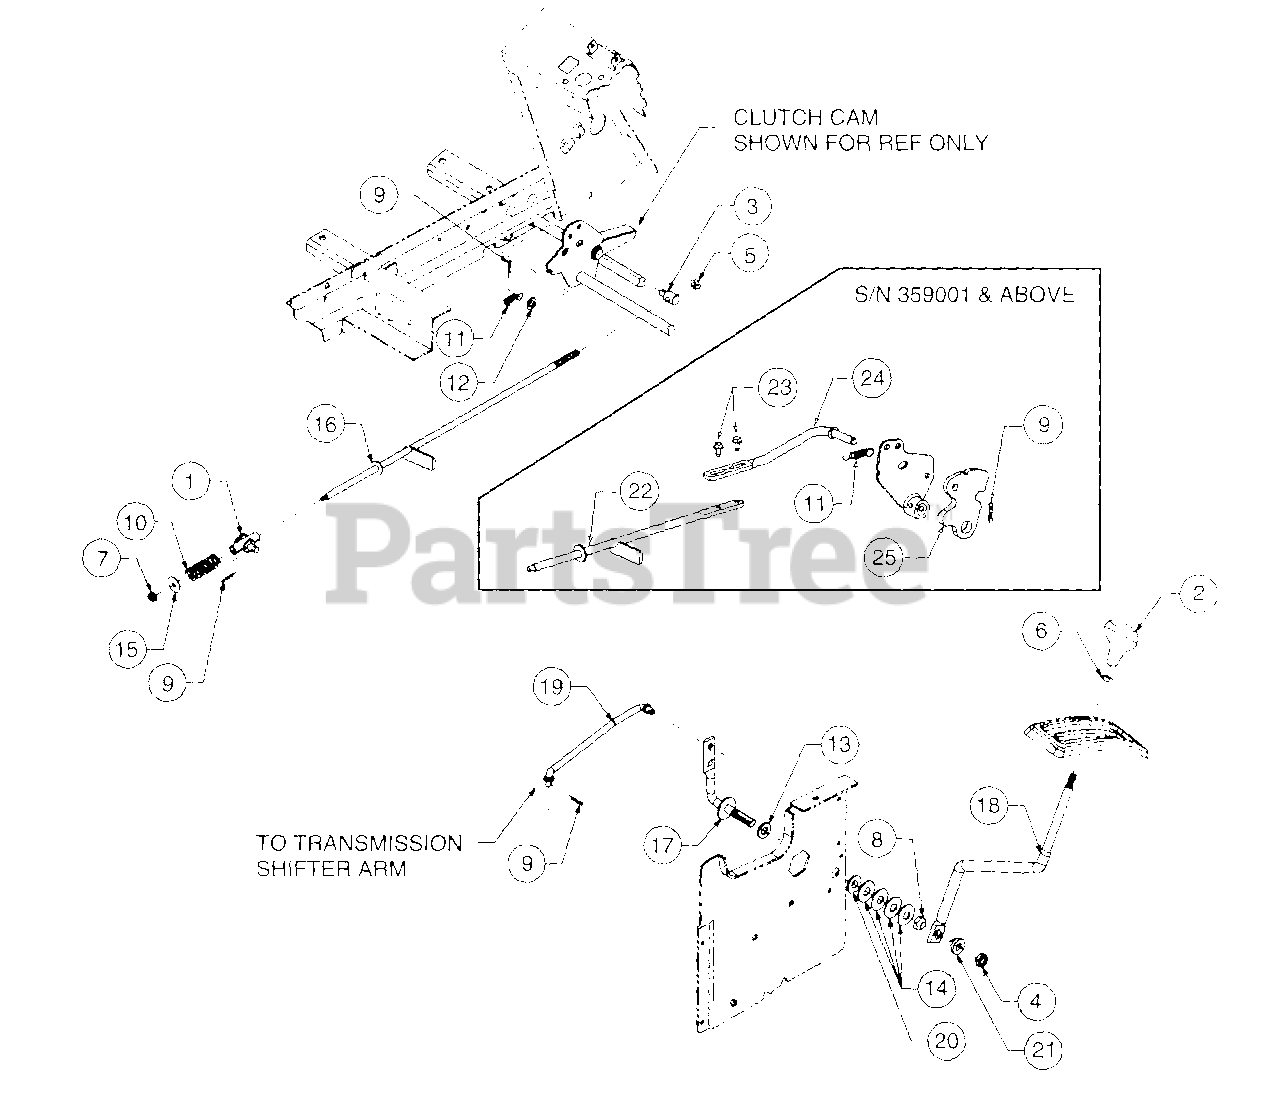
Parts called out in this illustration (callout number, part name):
1	Pivot Assy, Sleeve
2	Knob, Shifter
3	Ferrule, Adjustment
4	Nut, Hex Top Lock, 1/2-20
5	Nut, Hex Jam, 3/8-24 GR5
6	Nut, Hex Jam, 3/8-16 GR5
7	Nut, Hex Flange Lock, 1/4-20
8	Nut, Hex, 1/2-20
9	Pin, Internal Cotter, 5/16 x 1.12
10	Spring, Compression, .63 ID x 2.0 Lg
11	Spring, Extension, .38 OD x 1.44 Lg
12	Washer, Flat, .406 x .75 x .063
13	Washer, Flat, .510 x 1.0 x .125
14	Washer, Bell, .406 x .75 x .063
15	Washer, Flat, .265 x 1.0 x .030 Hdn
16	Rod, Clutch Adjustment
17	Rod, Shift
18	Rod, Gear Selector
19	Link, 6-Speed Shifter
20	Bushing, Shoulder
21	Hub, Shift
22	Rod, Clutch
23	Screw, Hex Wash Hd Tapp, 1/4-20 x .5
24	Rod, Front Control
25	Plate, 6-Speed Cruise
